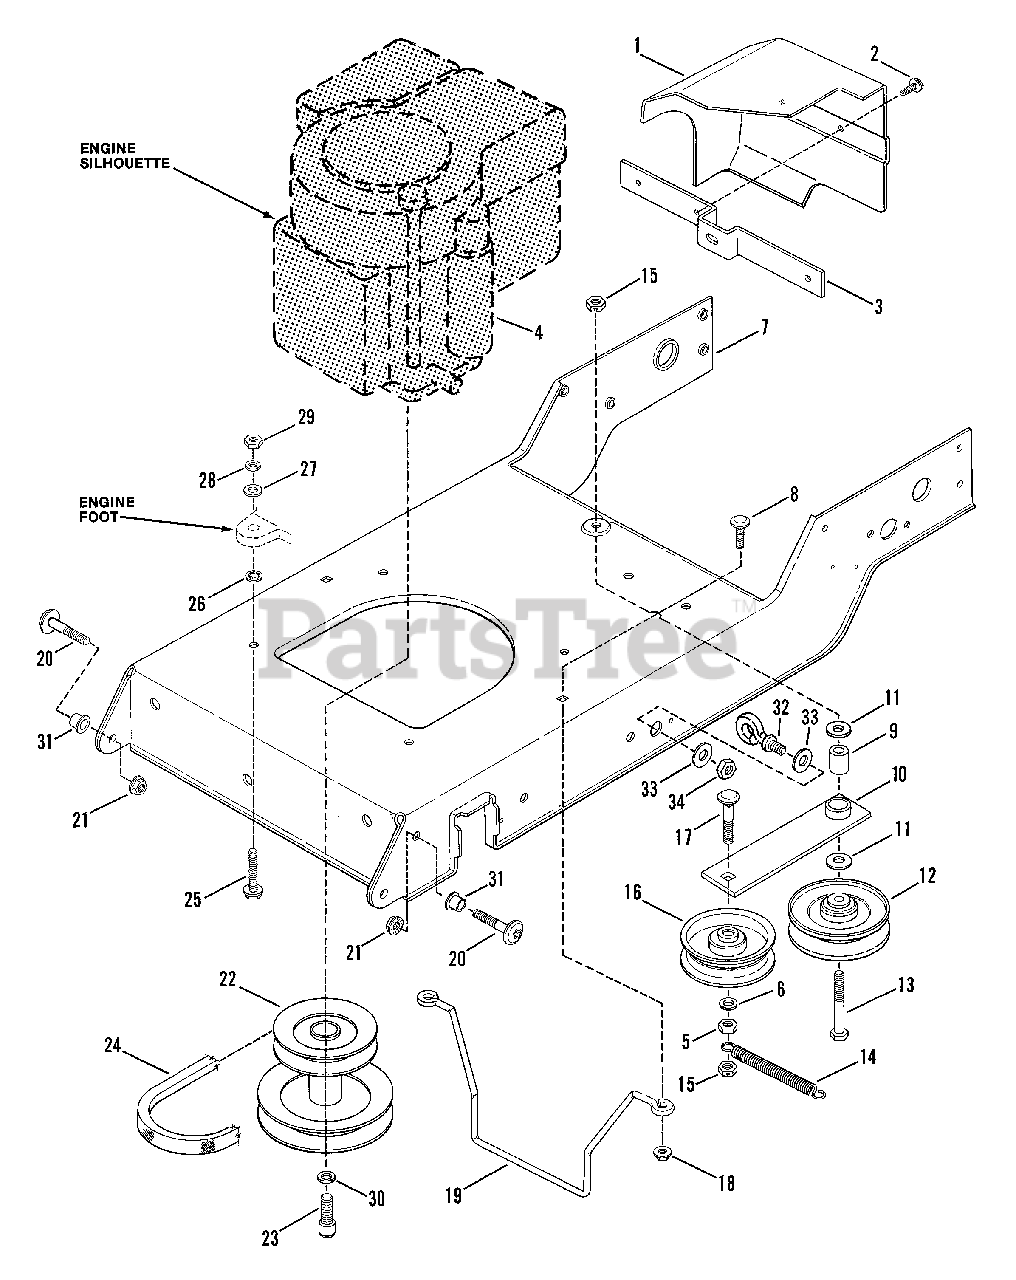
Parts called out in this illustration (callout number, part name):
1	HEAT SHIELD
2	SCREW, #10-24x1/2" H.W.S.T.
3	BRACKET, Heat Shield
5	NUT, 3/8-16 Hex
6	LOCKWASHER, 3/8 Split
7	BASE, Engine
8	BOLT, 5/16-18x3/4" Short Neck Carriage
9	BUSHING, Idler
10	ARM, Idler
11	WASHER, 3/8" Flat
12	PULLEY, Idler, 4" O.D.
13	BOLT, 3/8-16x2-1/4" Hex
14	SPRING, Idler Arm
15	LOCKNUT, 3/8-16 Hex, Center Lock
16	PULLEY, Idler, 3-3/4" O.D.
17	BOLT, 3/8-16x2-112" Short Neck Carriage
18	LOCKNUT, 5/16-18 Hex Flange
19	GUIDE, Belt
20	SCREW, Shoulder, 3/8-16x1-5/8"
21	LOCKNUT, 318-16 Hex Flange
22	PULLEY ASSEMBLY, Engine
23	CAPSCREW, 7/16-20 Hex Socket Head
24	V-Belt, Traction Drive, LT12D 41 (Before Serial No. 05003133 Only)
24	V-Belt, Traction Drive, all LT12D 33 (& LT12D41 Serial No. 05003133 & Later)
25	SCREW, 5/16-18x1-1/2" Hex Head Cap
26	RETAINER, Bolt
27	WASHER, 5/16 Flat
28	LOCKWASHER, 5/16 Split
29	NUT, 5/16-18 Hex
30	LOCKWASHER, 7/16" Split
31	BUSHING
32	EYE-BOLT
33	WASHER, 5/16" x 1-1/4" x 3/32" Flat
34	LOCKNUT, 5/16-18 Hex
